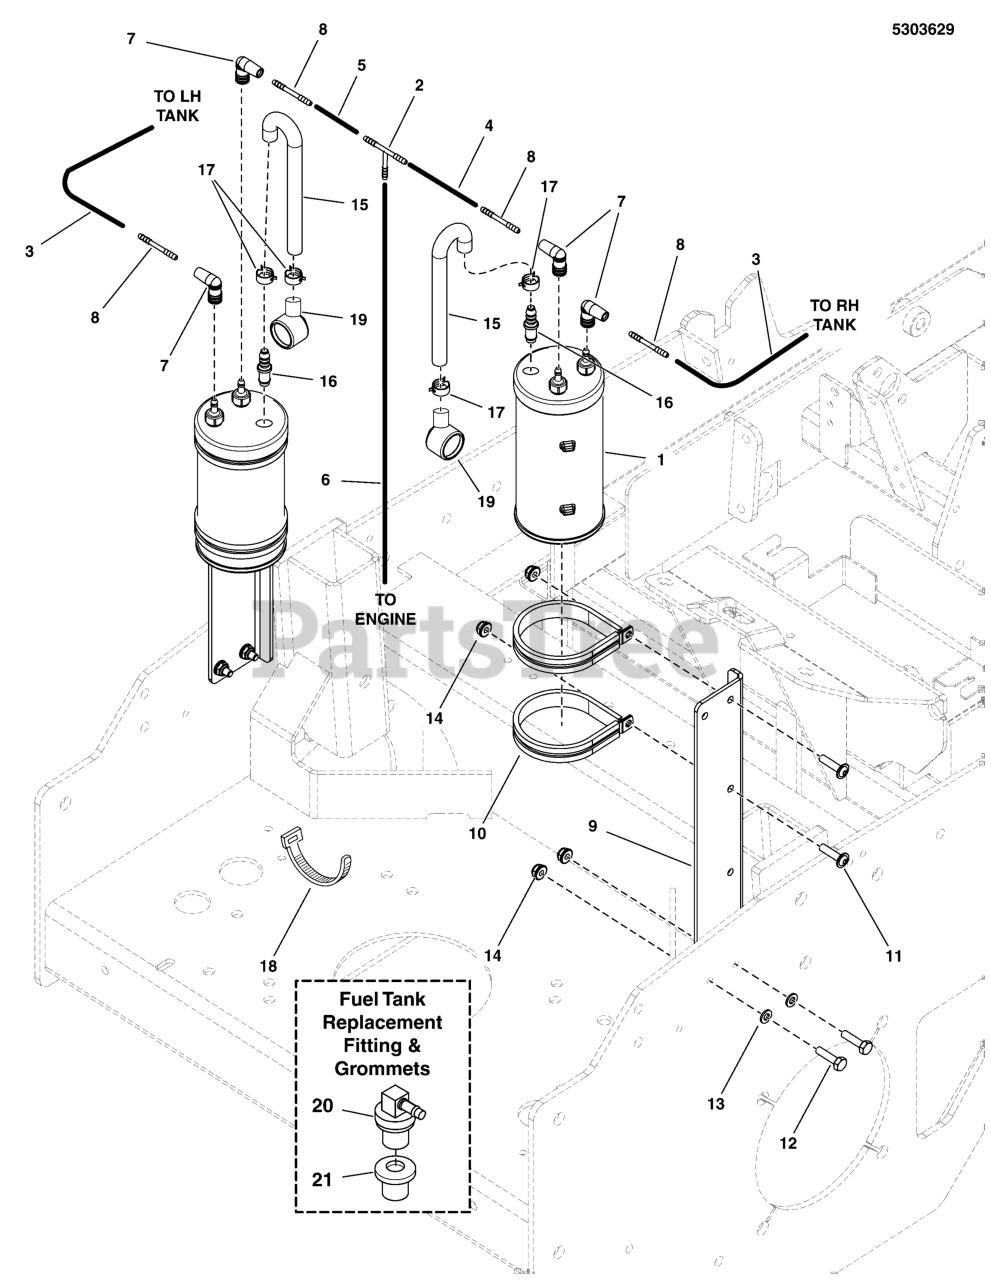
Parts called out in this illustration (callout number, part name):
1	CNSTR, CARB, 6 GAL
2	FITTING, 3/16" TEE, BARB TYPE, HDPE
3	HOSE, VAPOR, 5MM ID, 7.50 LG
4	HOSE, VAPOR, 5MM ID, 40.00 LG
5	HOSE, VAPOR, 5MM ID, 16.50 LG
6	HOSE, VAPOR, 5MM ID, 22.00 LG
7	FITTING, 90 DEG, 3/16X3/16, SANTOPRENE
8	FITTING, STRAIGHT, 3/16X3/16, PLASTIC
9	PLATE, EPA CANISTER MNT, S150XT - BLK
10	CLAMP, 3" ID, CUSHIONED, STAINLESS
12	BOLT, 1/4-20 X 1" GD5 CZ
13	WASHER, 1/4 SAE
14	NUT, 1/4-20 HEX NYLOCK FLANGE
15	HOSE, FORMED, EVAP CANISTER
16	FITTING, STRAIGHT, 10MMX10MM, PLASTIC
17	CLAMP, HOSE
18	TIE, SELF-LOCKING, 15"
19	DUST FILTER, CANISTER (SV)
20	REMOTE VENT ASSEMBLY
21	GROMMET (SV)
